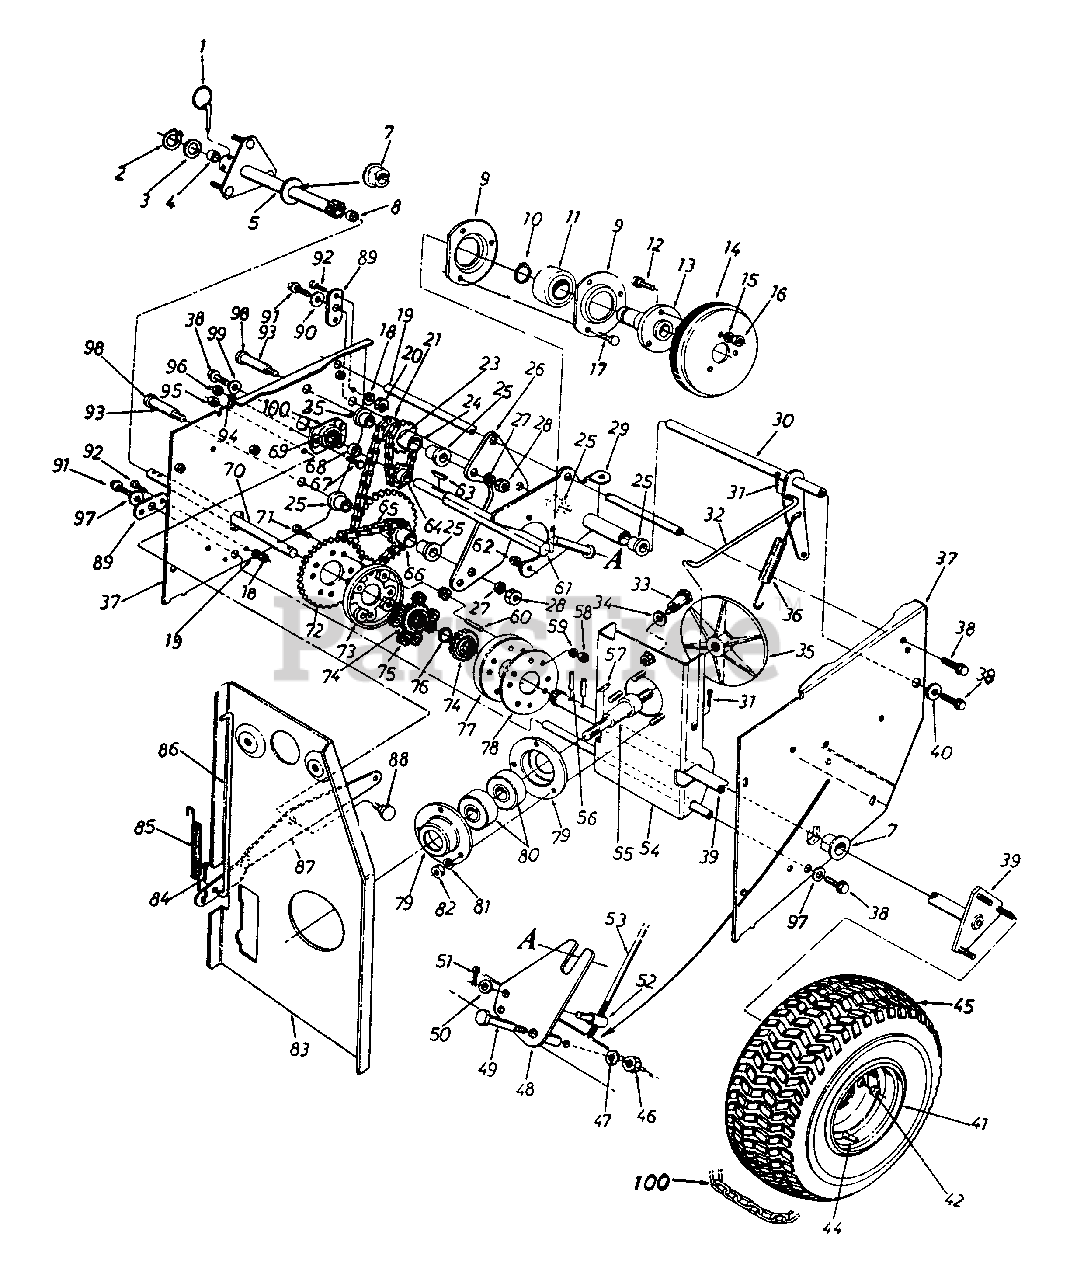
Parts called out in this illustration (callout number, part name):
1	Klik Pin 1/4 Dia. X 1.75
2	Snap Ring .625" Shaft
3	Flat Washer .640 I.D. X 1.24 O.D. x .06
4	Sleeve Bearing .63 I.D.
7	Flange Bearing w/Flats
8	Sleeve Bearing .63 I.D.
9	Bearing Housing - 52 MM
10	Snap Ring for 1.0" Shaft
11	Bearing - 25 MM
12	Hex Sems Scr. 5/16-18 x .75
13	Friction Wheel Adapter Plate
14	Friction Wheel Ass'y.
15	L-Wash. 5/16 I.D.
17	Hex Scr. 1/4-28 x .625" Lg.
18	L-Wash. 1/4 I.D.
19	Sliding Support Axle
20	Hex Nut 1/4-20
21	#420 Chain 1/2" Pitch x 44 Links
23	#41 Chain .50 Pitch x 20 Links - Endless
24	Sprocket Hub Ass'y. 9 & 14 Teeth
25	Flange Bearing .63 I.D.
28	Hex Nut 3/8-24
29	Sliding Linkage Bracket Ass'y.
30	Drive Clutch Bracket Ass'y.
31	Int. Cotter Pin 5/16 Dia.
32	Drive Clutch Rod .31 Dia. x 7.38
33	Shoulder Screw .498 Dia. x 1.64 Lg.
34	Bell-Washer .400 I.D. x .88 O.D. x .06
35	Aluminum Drive Plate
36	Idler Extension Spring
39	Differential Shaft Ass'y.
40	Flat Washer .344 I.D. x .625 O.D. x .063
41	Rim Only - 16"
42	Hex Nut 3/8-24 (Cone)
44	Air Valve
45	Wheel Ass'y. Comp. 16 x 6.5
46	Hex Jam Nut 3/8-16
47	L-Wash. 3/8 I.D.
50	Flat Washer .344 I.D. x .625 O.D. x .063
51	Cotter Pin 3/32 x .75
52	Adjustment Ferrule
53	Shift Rod .312 Dia x 29.0 Lg.
56	Spring Spiral Pin 3/16 Dia. x 1.25
57	#61 Hi-Pro Key 3/16 X 5/8
58	Hex Nut 1/4-28
59	L-Wash. 1/4 I.D.
60	Differential Pin
61	Hex Shaft
62	Hex Ins Jam L-Nut 1/4-28
63	#4 Hi-Pro Key 3/32 x 5/8
64	Center Sprocket - 8 Teeth
65	#420 Chain 1/2" Pitch x 37 Links
65	Master Link for #420 Chain
66	Sprocket Hub Ass'y. - 9 & 32 Teeth
67	Hex Screw 1/4-20 x .62
68	Spacer .51 I.D. x .69 O.D. x .44
69	Ball Brg. .5 I.D. x 1.38 O.D. x .44
70	Differential Connecting Shaft
71	Hex Bolt 1/4-28 x 1.75" Lg.
72	Sprocket 28 Tooth
73	Differential Housing Halves
74	20th Spur Gear
75	9th Spur Gear
76	Flat Washer .640 I.D. x 1.24 O.D. x .06
77	Differential Housing Halves
78	Differential Hsg. Support Plate
79	Brg. Housing 1.85" I.D.
80	Ball Bearing .787 I.D. x 1.85 O.D. x .56
81	L-Wash. 5/16 I.D.
82	Hex Nut 5/16-18
83	Engine Plate Ass'y.
84	Int. Cotter Pin 5/16 Dia.
85	Brake Return Ext. Spring 3.18" Lg.
86	Auger Clutch Rod
87	Auger Clutch Bracket
88	Shoulder Scr. .625 Dia. x .170
89	Pivot Axle Bracket
90	Flat Washer .344 I.D. x .625 O.D. x .063
91	Hex L-Bolt 5/16-18 x .62
92	Hex Screw 1/4-20 x .62
93	Sprocket Hub Tubing 3/8 I.D. x 5/8 O.D. x 1
94	L-Wash 1/4 I.D.
95	Hex Cent L-Nut 3/8-16
96	Hex Nut 1/4-20
97	Flat Washer .344 I.D. x .875 O.D.
98	Hex Screw 3/8-24 x 2.75
99	Bell-Washer .345 I.D. x .88 O.D. x .06
100	Tire Chain
